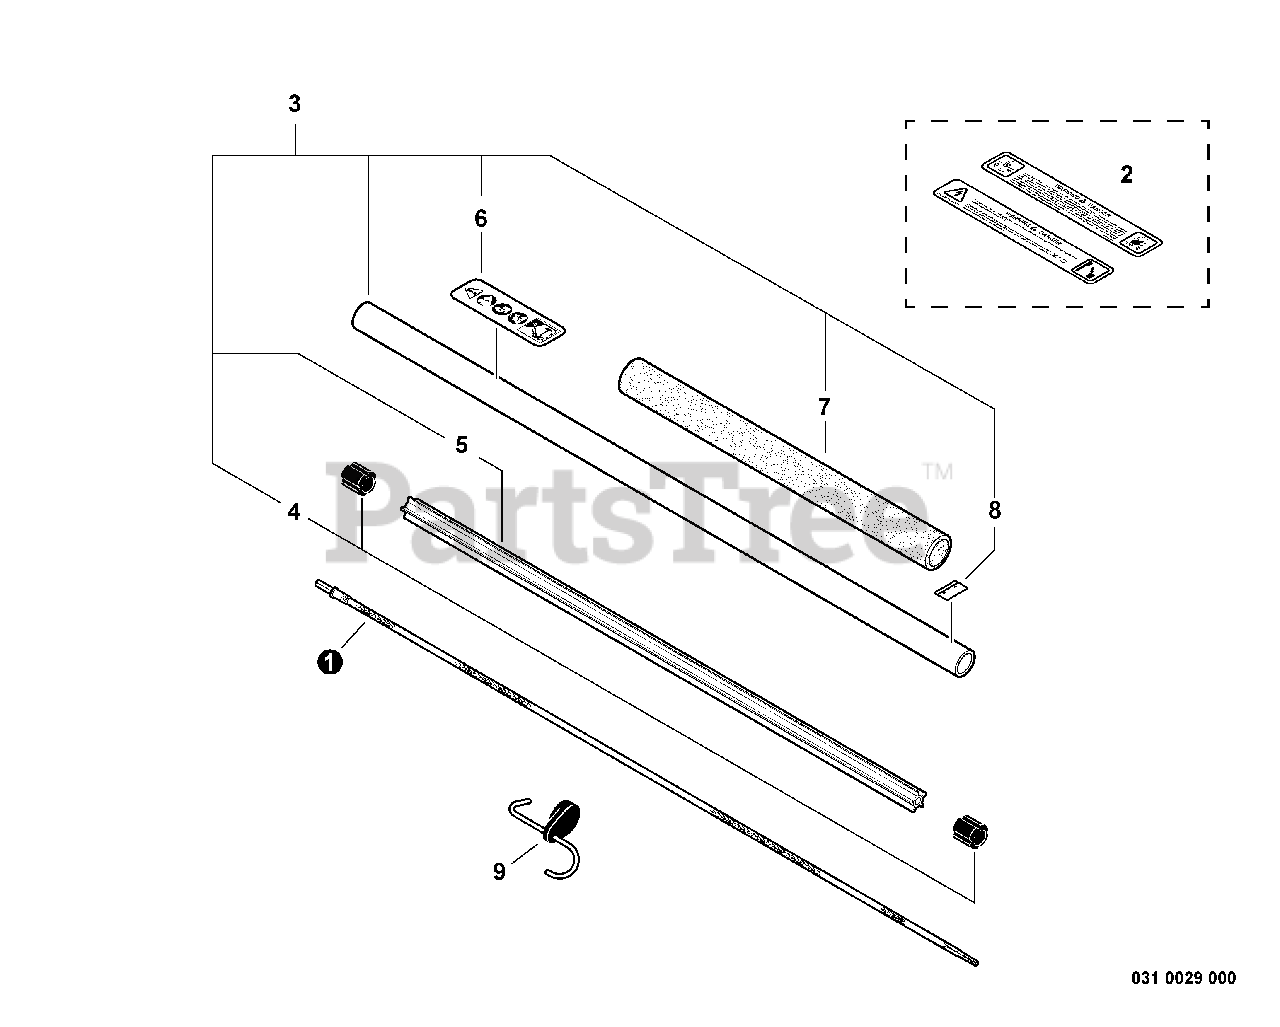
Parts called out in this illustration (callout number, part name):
1	DRIVESHAFT - FLEXIBLE
2	LABEL - CAUTION
2	LABEL, CAUTION
3	MAIN PIPE ASSY
5	LINER - FLEXIBLE
6	LABEL, CAUTION
7	GRIP, HANDLE
8	LABEL - ALIGNMENT
9	HANGER, ATTACHMENT
